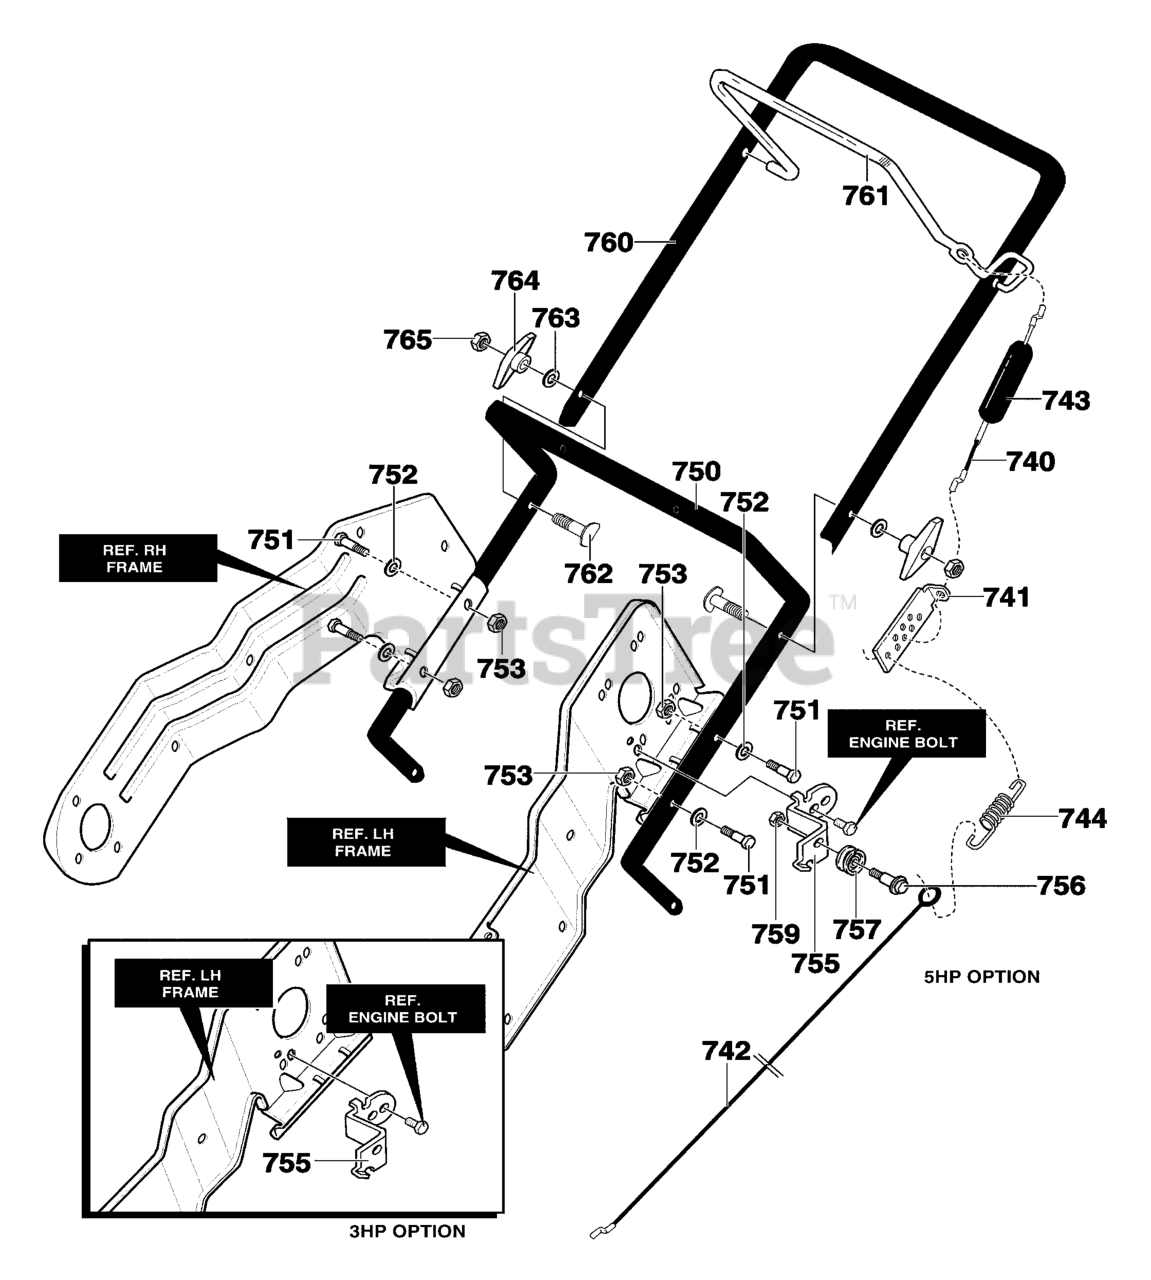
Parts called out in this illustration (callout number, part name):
740	CABLE, UPPER
741	BRACKET, CABLE ADJ
742	CABLE, LOWER CONTROL
743	BOOT, CLUTCH SPRING
744	SPRING, EXTENSION
750	HANDLE, LOWER
751	SCREW, 1/4-20X1.25
752	WASHER, FLAT
753	NUT, 1/4-20
755	BRACKET, CABLE
757	PULLEY
759	NUT, 1/4-20 YZ
760	UPPER HANDLE with Foam Grip
761	BAIL, CONTROL
763	WASHER, FORM
764	KNOB, T 3.00 WD
765	NUT, 5/16-18
